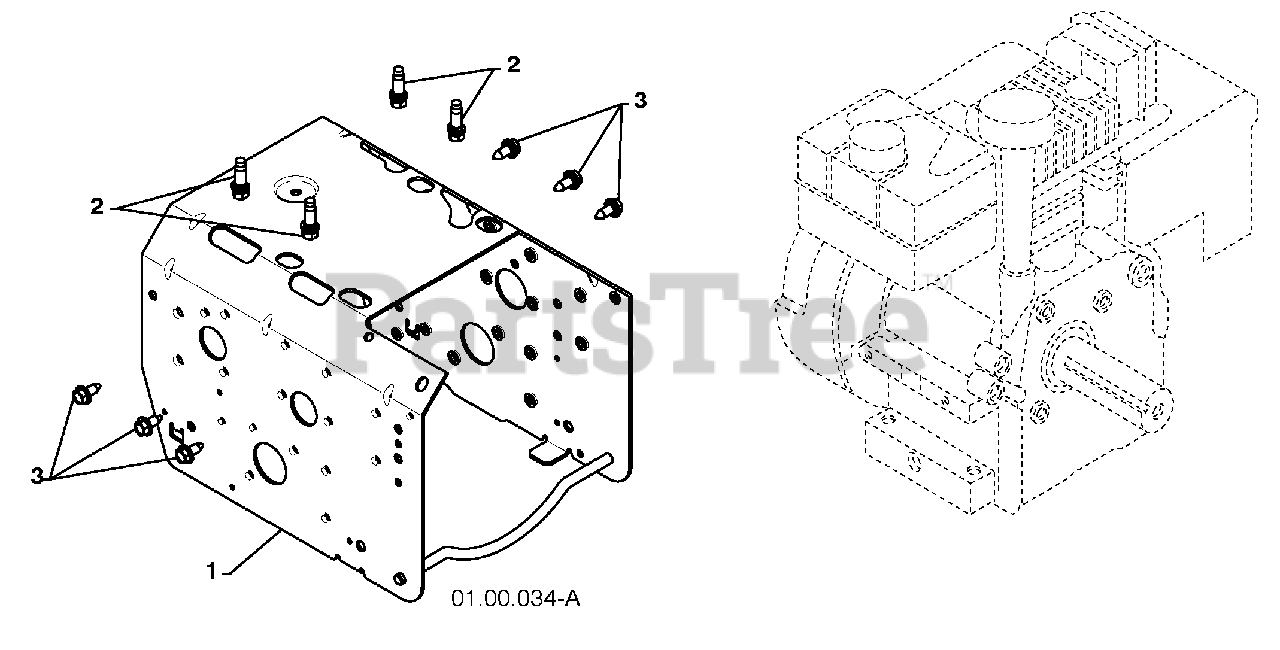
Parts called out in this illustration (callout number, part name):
1	FRAME
2	BOLT 3/8-16
3	SCREW 5/16-18 X .750
